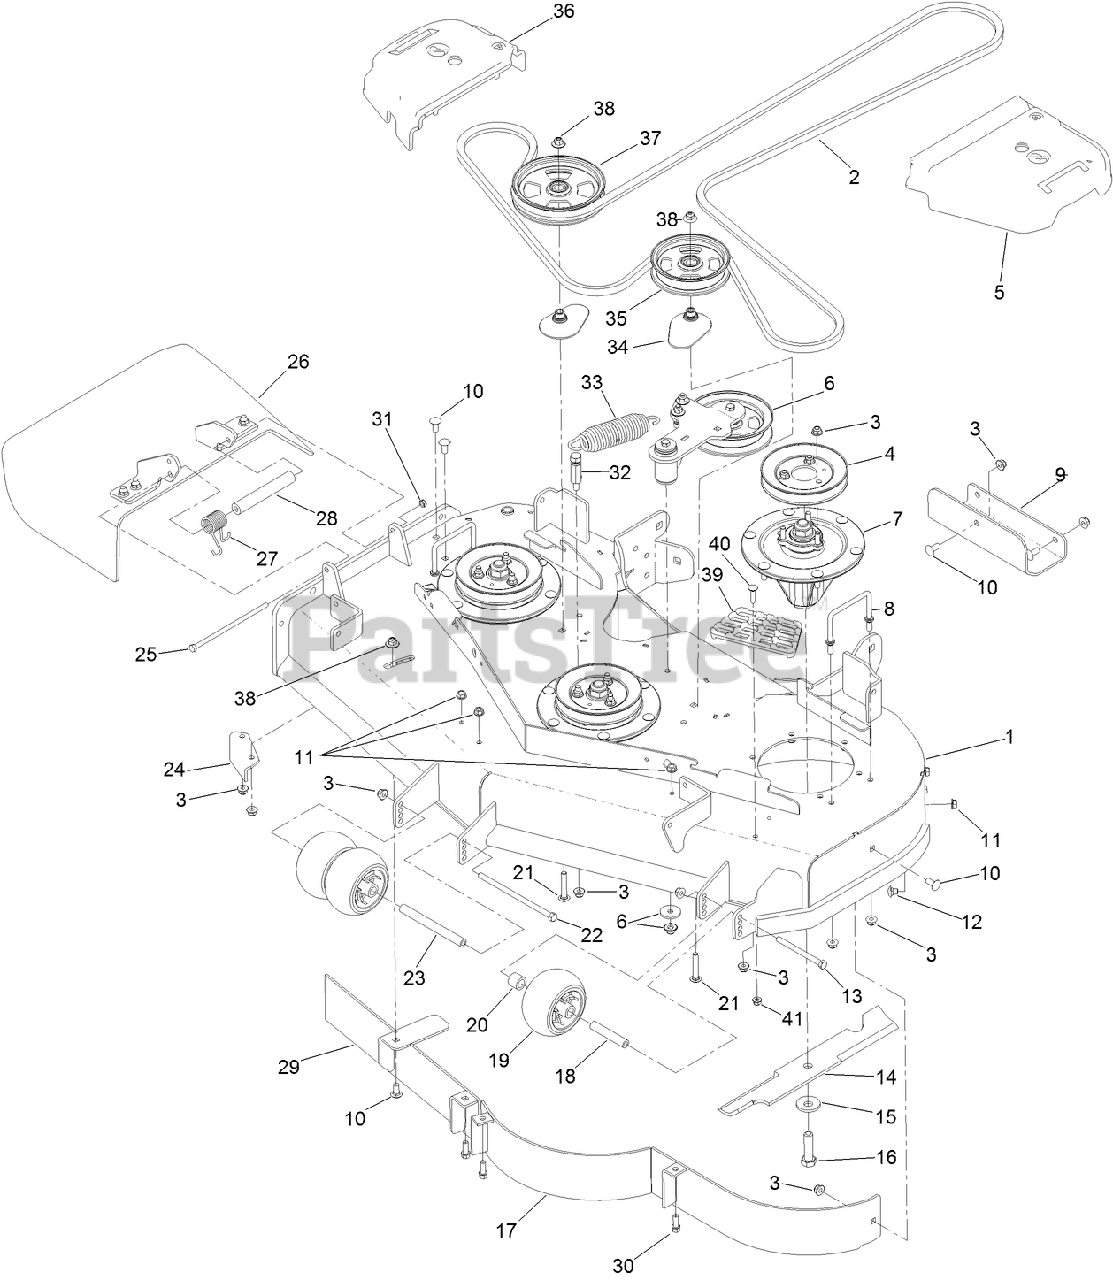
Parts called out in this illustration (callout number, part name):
1	DECK DECAL ASM
2	BELT-V
3	NUT-HF, NI
4	PULLEY
5	COVER-BELT, LH
6	IDLER ARM ASM
7	SPINDLE ASM
8	WIREFORM-COVER
9	PLATE-SKID
10	SCREW-CARR
11	NUT-HHF, WHIZ
12	SCREW-CARR
13	SCREW-HH
14	BLADE-16.5 INCH (HIGH FLOW)
15	WASHER-BLADE BOLT, HEAVY
16	SCREW-BLADE
18	TUBE-SPANNER
19	ROLLER-SCALP, ANTI
20	TUBE-SPACER
21	BOLT-CARR, SHORT NECK
22	SCREW-HH
23	SPACER-WHEEL
24	BAFFLE-DISCHARGE
25	SCREW-HH
26	RUBBER DEFLECTOR ASM
27	SPRING-TORSION
28	SPACER
29	BAFFLE ASM
31	NUT-LOCK, NI
32	ANCHOR-SPRING, TALL
33	SPRING-EXTENSION
34	SPACER-PULLEY
35	PULLEY-IDLER,FLAT
36	COVER-BELT, RH
37	PULLEY-IDLER, FLAT
38	NUT-FLANGE, NI
39	STEP-DECK
40	SCREW-CARR
41	NUT-HF, NI
